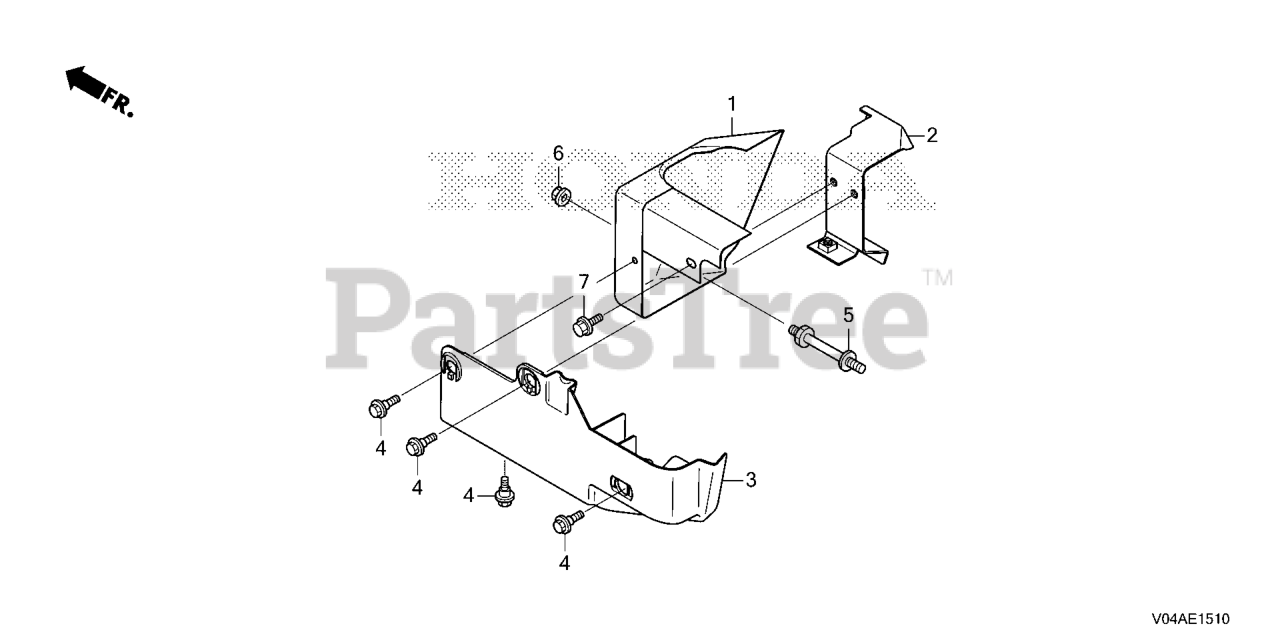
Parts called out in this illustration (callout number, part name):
1	SHROUD, FR.
2	STAY, SHROUD
3	GUIDE, AIR
4	BOLT, FLANGE (6MM)
5	BOLT, SHROUD (LOWER)
6	NUT, FLANGE (6MM)
7	BOLT, FLANGE (6X10)
